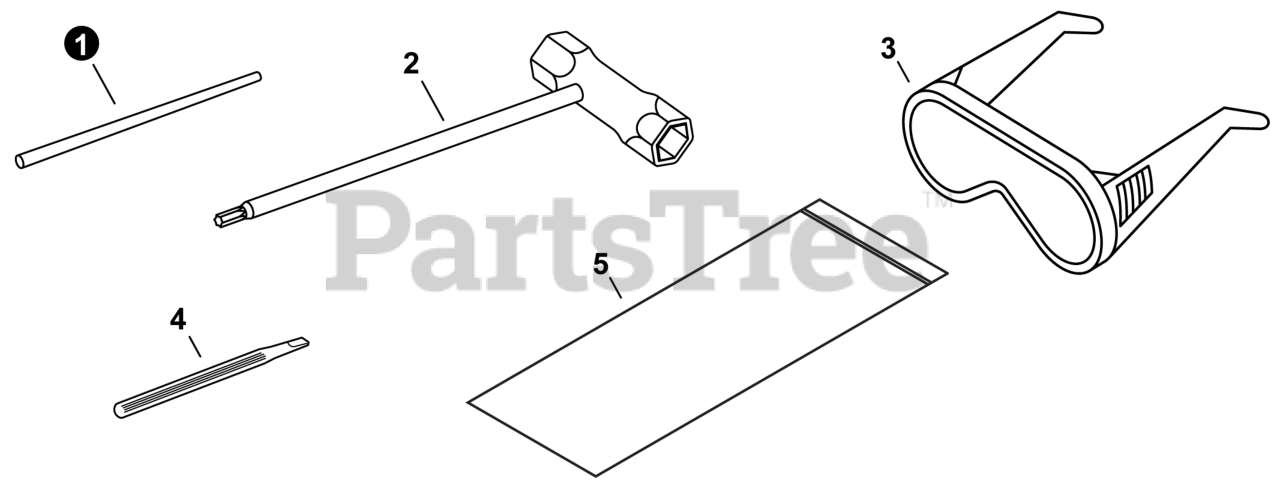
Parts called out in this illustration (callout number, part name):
1	TOOL, LOCKING 5x120 MM
2	T-WRENCH
3	GLASSES, SAFETY
4	SCREWDRIVER, PLASTIC
5	BAG, TOOL
